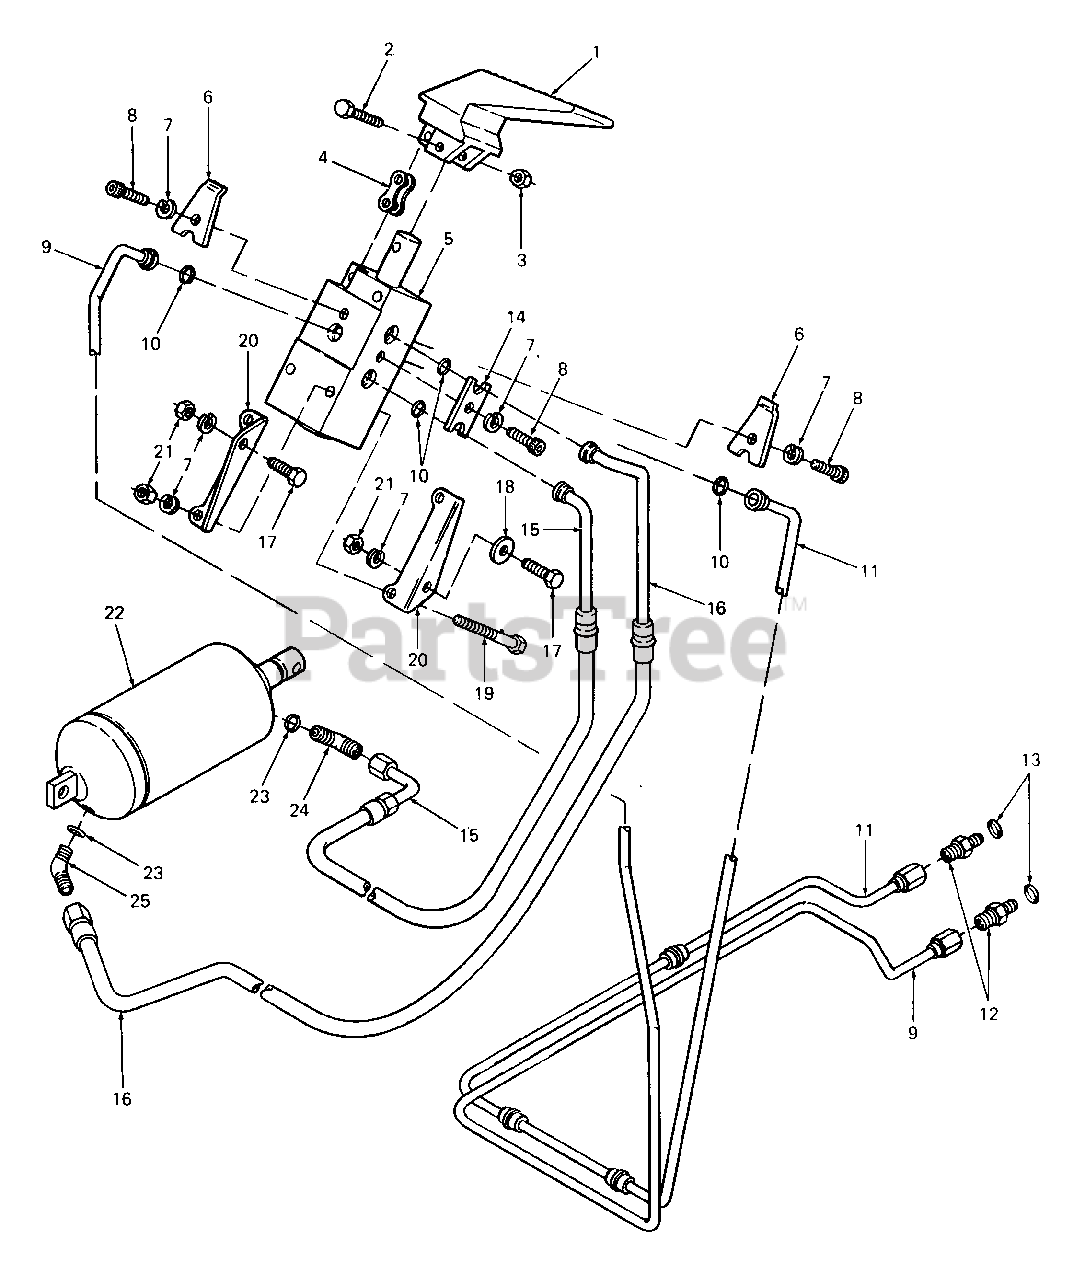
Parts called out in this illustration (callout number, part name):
1	Handle, Valve
2	Screw, Hex Cap, #10-24 X 1.0 Lg
3	Nut, Hex Center Lock, #10-24
4	Link, Chain
5	Valve, Lift
6	Clamp, Single
7	Washer, Lock, 1/4
8	Screw, Socket Hd Cap, 1/4-20 X .62 Lg GR8
9	Tube Assy, Return
10	O-Ring, .301 X .070 Dia
11	Tube Assy, Pressure
12	Connector, 37 Degree Tube
13	O-Ring, 3/8 OD Tube
14	Clamp, Double
15	Hose, Cylinder - Contracting
16	Hose, Cylinder - Extending
17	Screw, Hex Cap, 1/4-20 X .62 Lg GR5
18	Washer, Bell, .265 X .75 X .062 Thk
19	Screw, Hex Cap, 1/4-20 X 2.25 Lg
20	Bracket, Valve Mtg
21	Nut, Hex, 1/4-20 GR5
22	Cylinder, Hydraulic
23	O-Ring, 1/4 OD Tube
24	Elbow, 90 Degree w/O-Ring
25	Elbow, 45 Degree w/O-Ring
